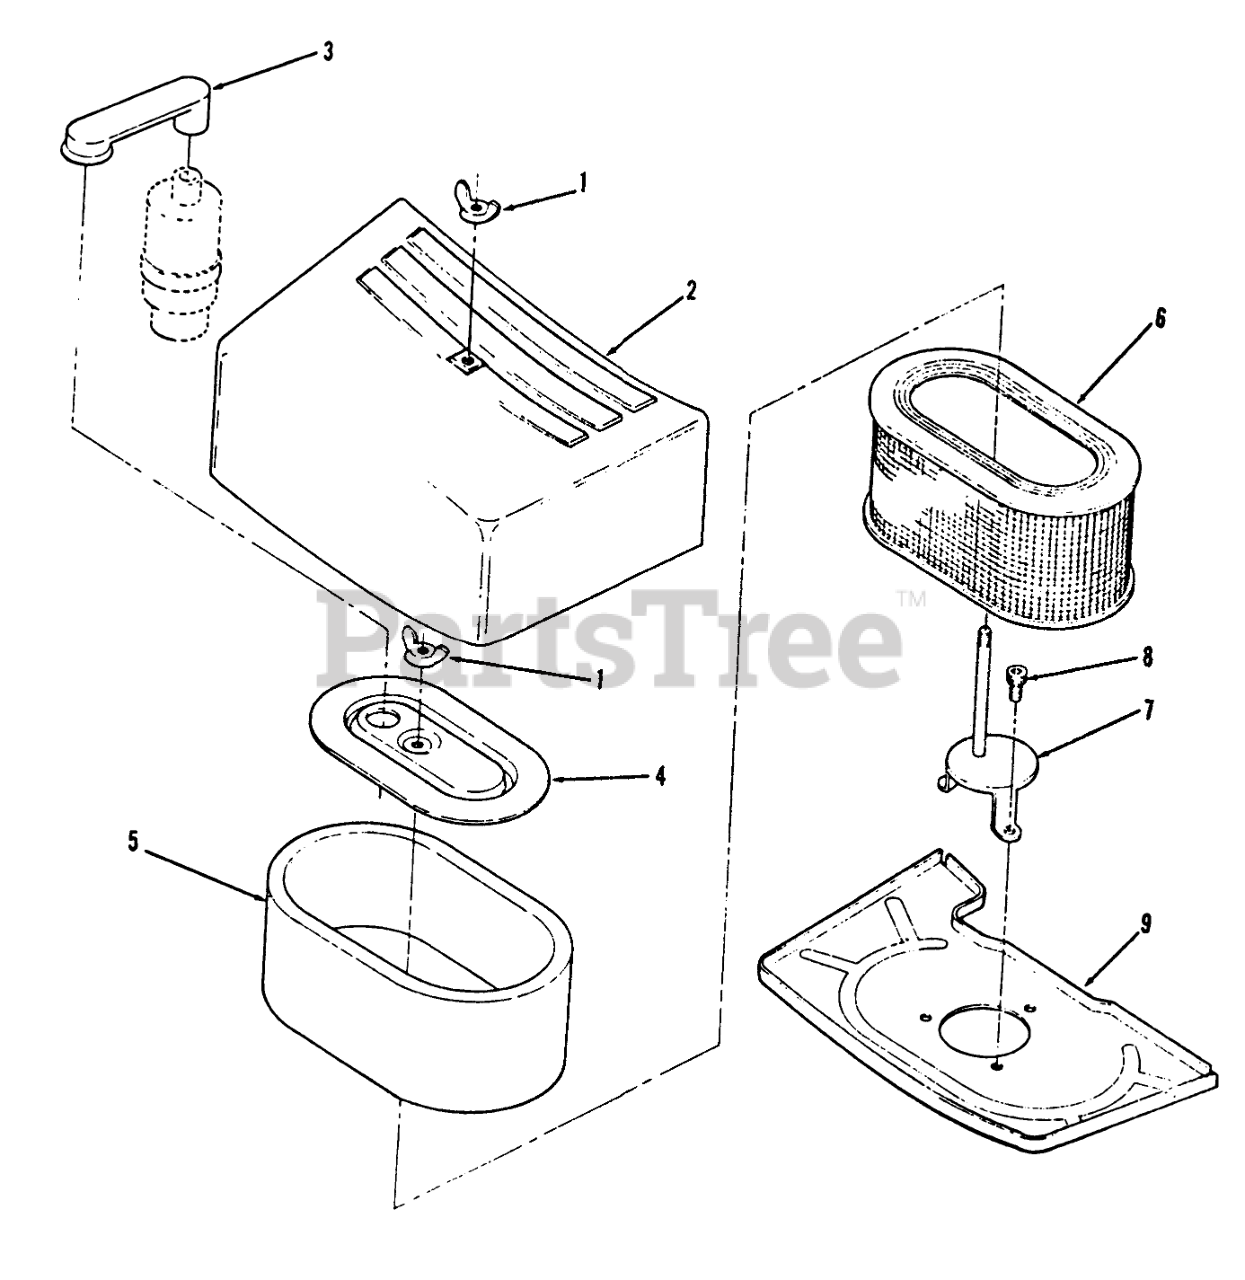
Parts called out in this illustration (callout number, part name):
1	Nut-Wing
2	Hood
3	BREATHER-TUBE
4	ELEMENT-COVER (ZINC)
5	ELEMENT-WRAPPER
6	Support
7	HOOD-SUPPORT
8	SOCKET-HEAD CAP SCRW
9	PAN (ZINC)
